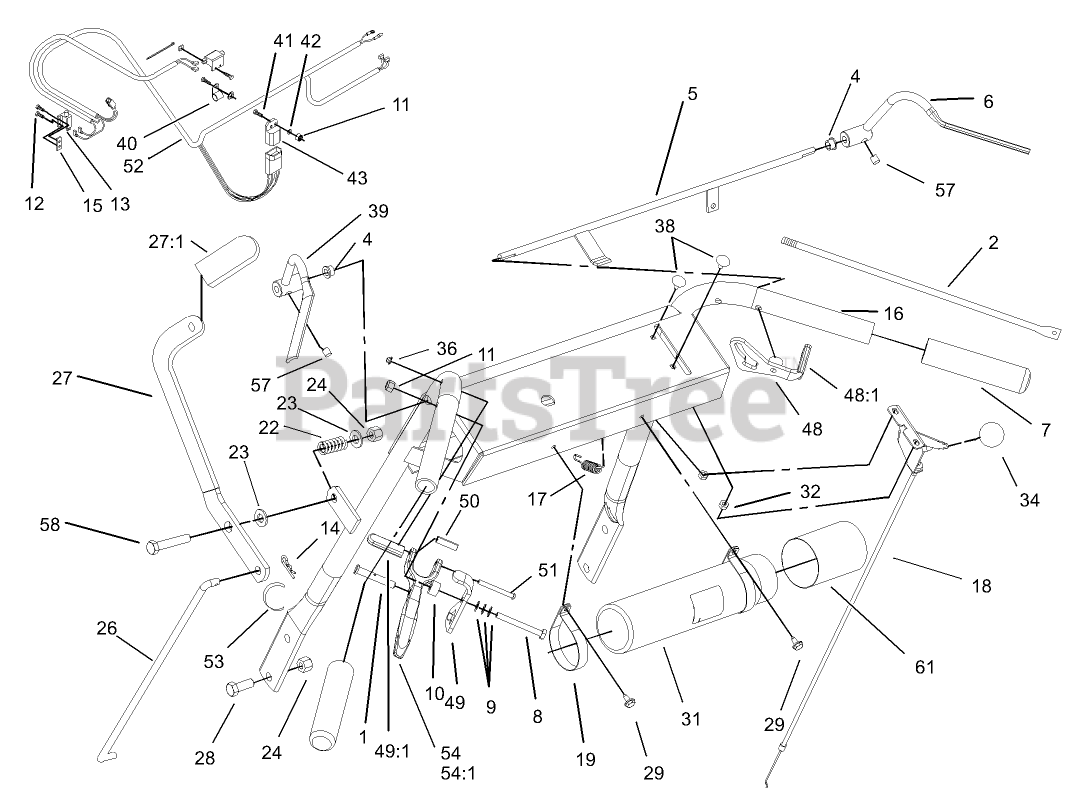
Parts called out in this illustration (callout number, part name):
1	PIN-CLEVIS
2	Linkage-Wheel, Drive
4	BUSHING-NYLON
5	ROD-CONTROL, OPERATOR PRESENCE
6	LEVER-RH
7	Grip-Handle
8	SCREW-HH
9	WASHER-SPRING
10	SPACER
11	NUT-LOCK, NI
12	SCREW-PPH
13	SWITCH-OPEN, NORMALLY
14	PIN-COTTER
15	PLATE-TAPPED
16	HANDLE ASM
17	SPRING-EXTENSION
18	Cable-Control, Throttle
19	CLAMP-R
22	SPRING-COMPRESSION
23	WASHER-FLAT
24	NUT-LOCK, NI
26	Linkage-Blade, Upper
27	LEVER ASM
27:1	GRIP-LEVER
28	SCREW-HH
29	SCREW-HWHTF
31	TUBE-MANUAL
32	NUT-LOCK, NI
34	KNOB-BALL
38	BOLT-CARR
39	LEVER-LH
40	CLIP-LOOM
41	SCREW-HH
42	WASHER-FLAT
43	MODULE-INTERLOCK
48	RH THUMB LATCH ASM
48:1	GRIP-LATCH
49	LH THUMB LATCH ASM
49:1	GRIP-LATCH
50	PIN-ROLL
51	PIN-LEVER, DRIVE
52	Harness-Wire
53	Clip-Cable
54	DRIVE LEVER ASM
54:1	GRIP-LEVER, DRIVE
57	SCREW-SET
58	SCREW-HH
61	CAP-HOUSING
